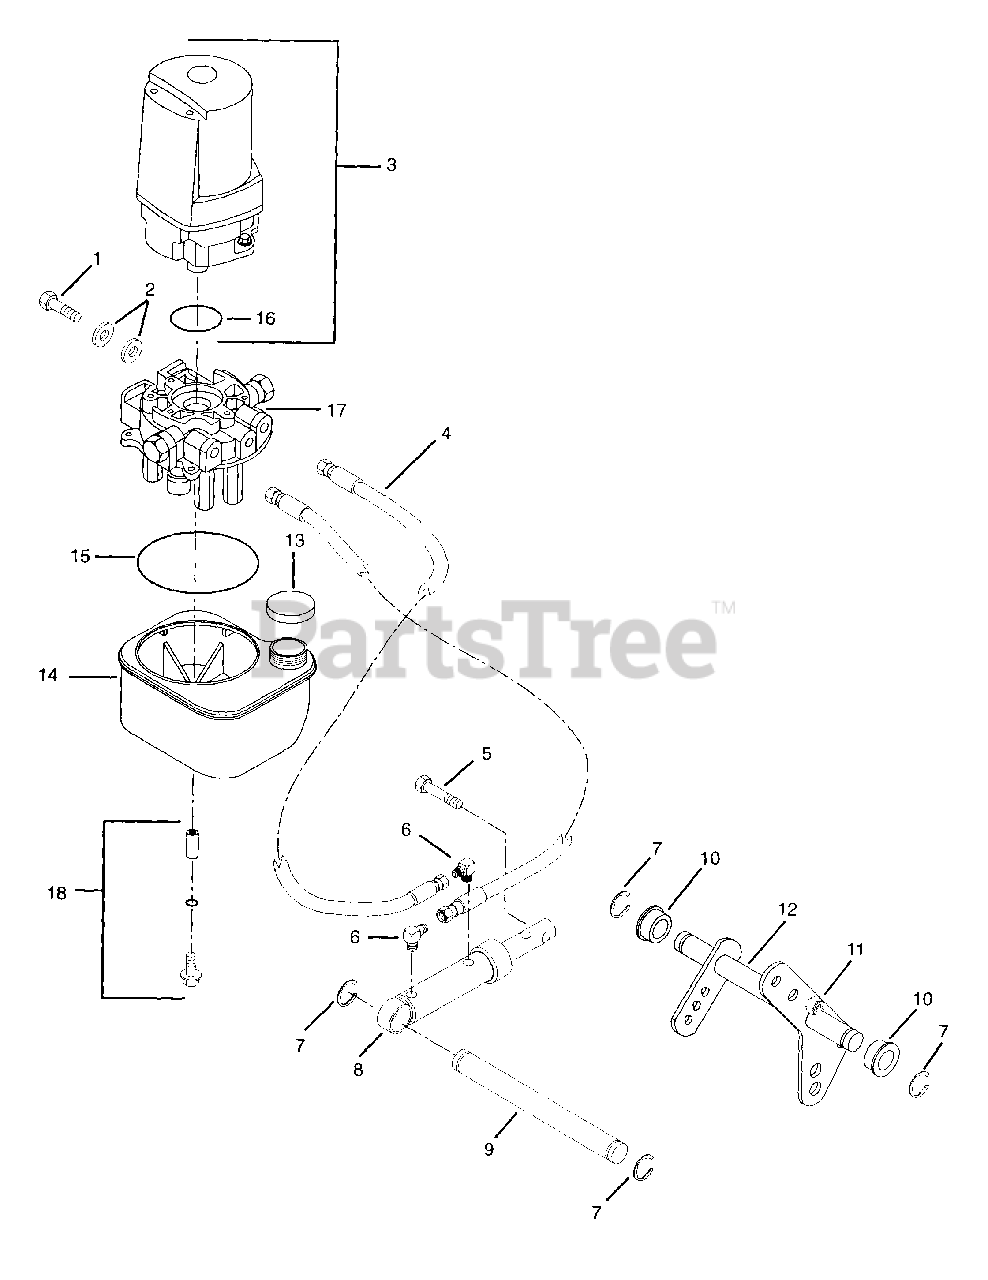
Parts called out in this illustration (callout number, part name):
1	Bolt-Hex .38-16 x 1.00
2	Washer-Flat-Steel .390 x .875 x .18
3	Motor Assembly
4	Assembly, Hose Pump to Cylinder
5	Bolt-Hex .50-13 x 2.00 Grade 5
6	Adapter 2503-4-4
7	Ring-Retaining-External .835 x .056
8	Cylinder, Hydraulic
9	Shaft, Hydraulic Cylinder
10	Bushing-Flange 1.020 x 1.385 x .75 x 1.75
11	Nut-Locking .50-13
12	Mower Lift Weldment
13	Reservoir Cap-Electric Hydraulic Pump
14	Reservoir Tank
15	Reservoir Seal O-Ring
17	Adapter Assembly
18	Screw, O-Ring and Spacer Assembly
